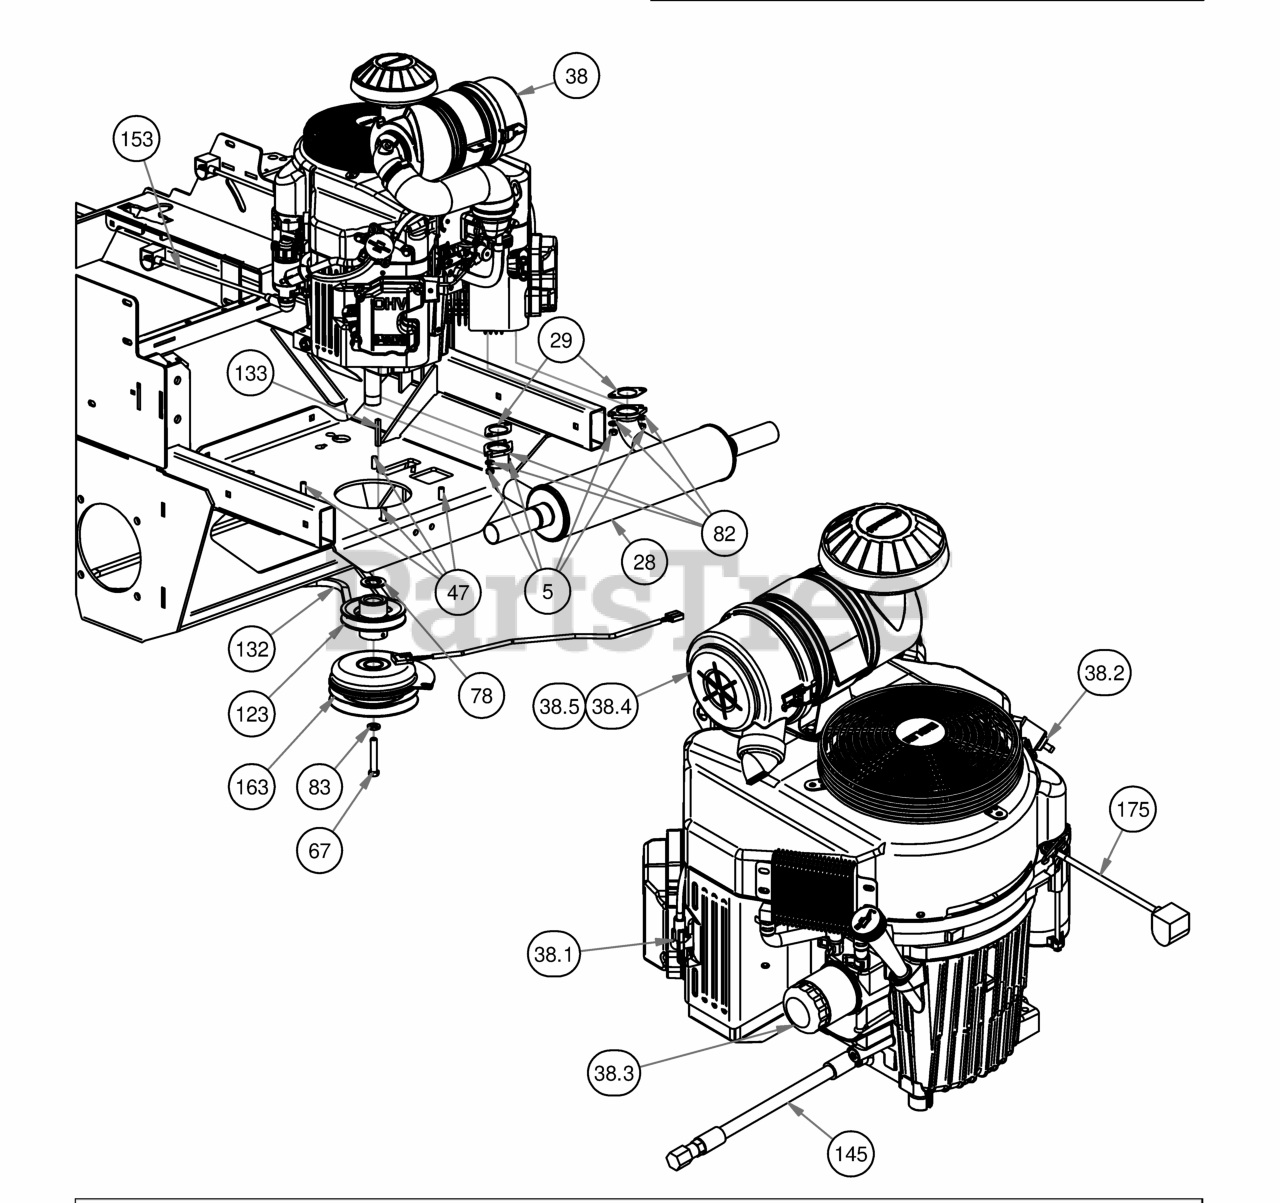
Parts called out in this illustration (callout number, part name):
5	M8-1.25 Zinc Nut
28	Muffler for Kawasaki FX1000
29	Exhaust Gasket
38	Kawasaki FX1000 Engine
38.1	Spark Plug - Kawasaki
38.2	Universal Inline Fuel Filter
38.3	Oil Filter
38.4	Canister Air Filter- Outer
38.5	Canister Air Filter- Inner
47	3/8 x 1 1/8 bolt
67	7/16" x 2 1/2" Hex Bolt
78	1 1/8" Flat Spacer
82	5/16" Lock Washer
83	7/16" Lock Washer
123	4 3/4 Motor Pulley
132	2019 Rebel Pump Belt
133	1/4 x 2 Square key Stock
145	Kawasaki Oil Drain
153	14" Red Battery Cable-Base Outlaw
163	Clutch Assembly
164	Clutch Pigtail
165	2019 Rigid Frame
175	Starter Cable
